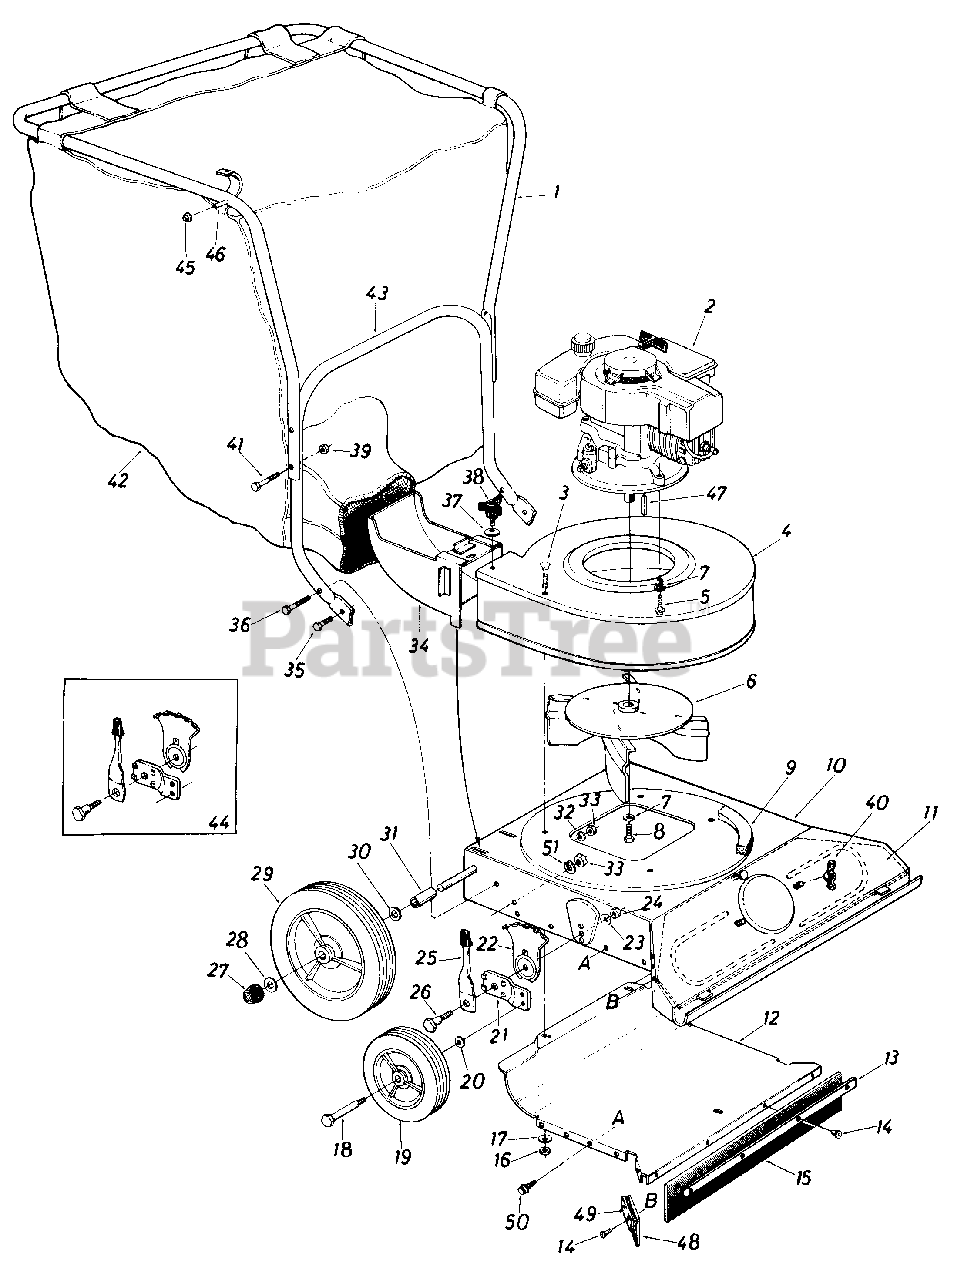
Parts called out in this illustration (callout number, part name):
1	Upper Handle (Painted)
2	Engine
3	Carriage Bolt 5/16-18 x .62" Lg.*
4	Blower Housing Ass'y.
5	Hex Tap Scr. 3/8-16 x 1.00" Lg.
6	Impeller Ass'y.
7	L.-Wash. 3/8" I.D.*
8	Hex Bolt 3/8-24 x 1.0" Lg. w/ Patch
9	P.V.C. Foam Strlp (4-Pcs. 12" Lg. )
10	Vacuum Deck Ass'y.
11	Front Baffle Ass'y.
12	Lower Baffle Ass'y.
13	Wiper Retaining Strip
14	Pop Rivet.188" Dia.
15	Nozzle Wiper Rear
16	Hex Nut 5/16-18 Thd.*
17	Bell.-Wash. .34" I.D. x.87" O.D.
18	Shld. Bolt 1/2" Dia. x 1.45" Lg. (3/8-16)
19	Wheel Ass'y. Comp. 8 x 1.75" - Front
20	Bell.-Wash. .39" I.D. x 1.12"O.D.
21	Wheel Pivot Bar
22	Index Plate
23	Bell.-Wash. .39" I.D. x 1.12"O.D.
24	Hex Nut 3/8-16 Thd.*
25	Spring Lever Ass'y. w/Knob
26	Shoulder Bolt .500" x 7/16" Lg. (3/8-16)
27	1 Push Cap .50" Rod (Black)
28	Fl.-Wash. 1/2" I.D. x 1.0" O.D. x .06
29	Wheel Ass'y. Comp. 10 x 1.75" - Rear
30	Fl.-Wash 1/2" I.D. x 1.0" O.D. x .06
31	Wheel Spacer 1/2" I.D. x 15/16" Lg.
32	Bell.-Wash. .39" I.D. x 1.12" O.D.
33	Hex Nut 3/8-16 Thd.*
34	Air Duct Ass'y.
35	Hex Bolt 3/8-16 x .75" Lg.*
36	Hex Bolt 3/8-16 x 1.50" Lg.*
37	Bell.-Wash. .34" I.D. x .87" O.D.
38	Thumb Scr. 5/16-18 x .75" Lg.
39	Hex Cent. L.-Nut 1/4-2 Thd.
40	Wing Nut 1/4-20 (Plastic)
41	Hex Bolt 1/4-20 x 1.75" Lg.*
42	Vacuum Bag (6.6 Bushel)
43	Lower Handle (Painted)
44	Height AdjusterAss'y. Comp. -R . H .
45	Push Speed Nut .25" Dia.
46	Stud Pin .250" Dia. x 1.75" Lg.
47	Sq. Key 3/16 x 3/16 x 1.00"Lg.
48	Nozzle Wiper Side
49	Wiper Retaining Strip
50	Hex Wash. Hd. "F" Tap Scr. #l10
51	L-Wash. 3/8" I.D.*
